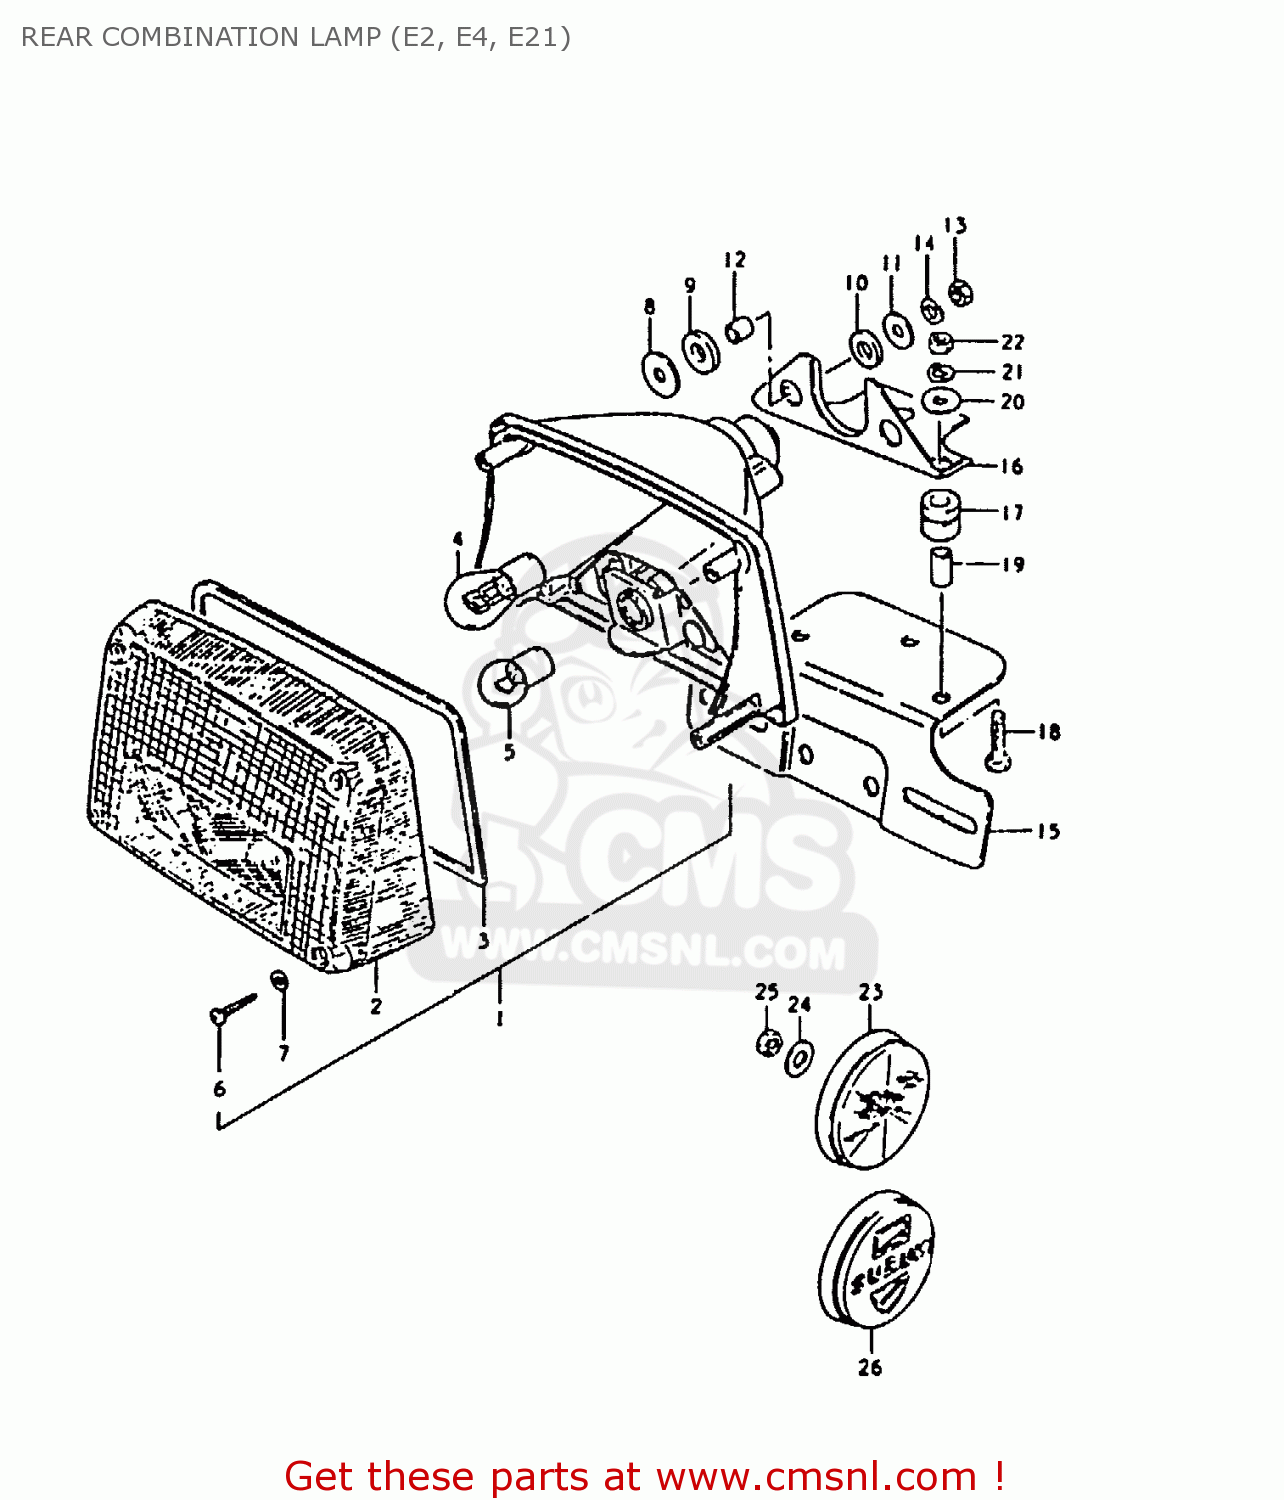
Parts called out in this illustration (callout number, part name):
1	LAMP ASSY, REAR COMBINATION
2	LENS
3	GASKET (NAS)
4	BULB 12V21/5W
5	BULB
6	SCREW
7	GASKET (NAS)
8	WASHER
9	CUSHION
10	CUSHION
11	WASHER(6,5X22X1.6)
12	SPACER(6.1X9X7.5)
13	NUT
14	LOCK WASHER
15	BRACKET, LICENCE PLATE
16	BRACKET,LICENSE PLATE
17	CUSHION, BRACKET
18	BOLT
19	SPACER (6.4X9X15.5)
20	WASHER
21	LOCK WASHER
22	NUT
23	REFLEX REFLECTOR,RR
24	WASHER
25	NUT
26	EMBLEM, REAR SIDE
